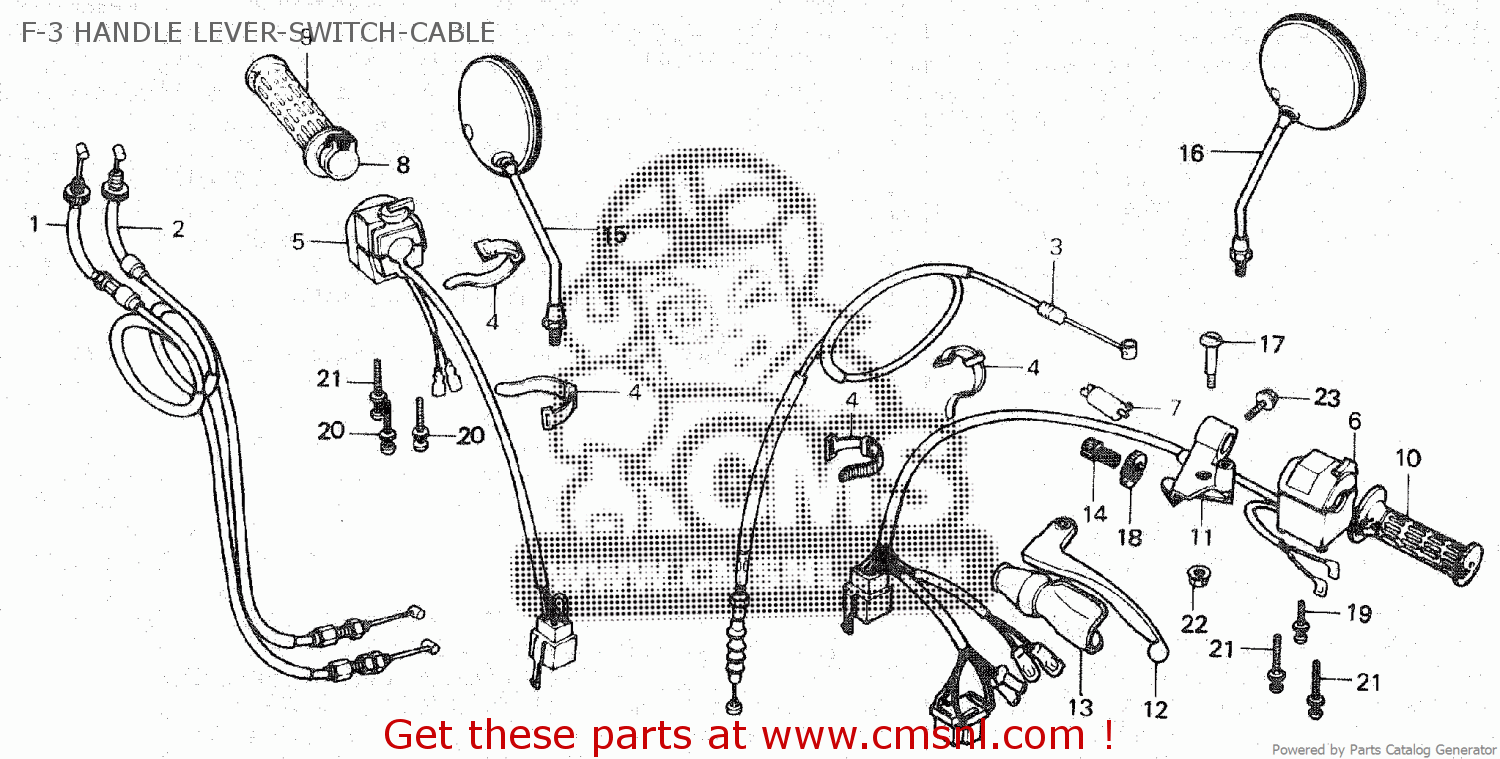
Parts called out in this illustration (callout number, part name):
1	CABLE.A,THROTTLE
2	CABLE B,THROTTLE
3	CABLE COMP,CLUTCH
4	BAND,BI WIRE
5	SW.,STARTER KILL
6	SW ASSY,WINKER
7	SWITCH,FR.LEVER
8	PIPE,THROTTLEGRIP
9	GRIP,R.HANDLE
10	GRIP,L.HANDLE
11	BRKT,L.HANDLE LEV
12	LEVER.,L. HANDLE
13	BOOT,HANDLE LEVER
14	BOLT.,CABLE ADJ
15	MIRROR,BACK
16	MIRROR,BACK
17	BOLT,HNDL,LEVER
18	NUT,FIXING
19	SCREW-WASHER,5X30
20	SCREW-WASHER,5X30
21	SCREW-WASHER,5X45
23	BOLT,FLANGE,6X25
